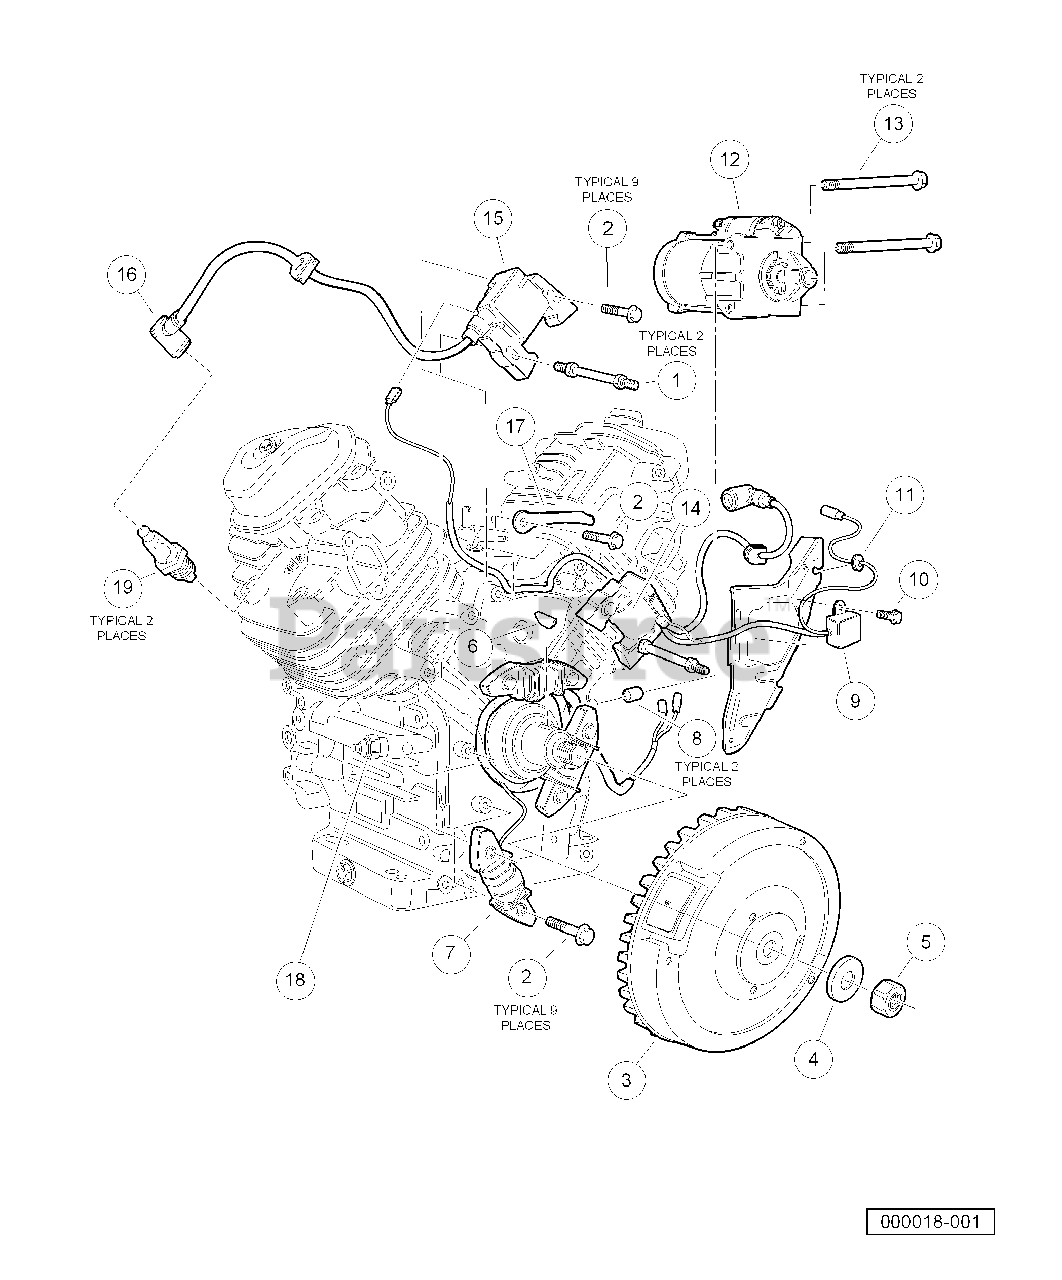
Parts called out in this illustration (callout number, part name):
1	Stud, Engine
2	Bolt, Flange Head, M6 X 1 X 32
4	Washer, M20
5	Nut, Flange, M20
6	Key, Special Woodruff, 25 X 18
7	Coil Assy, Charge, 12-Volt, 20-Amp
8	Pin, Dowel, 10x12
9	Diode Assembly
10	Bolt, Flange Head, M6 X 1 X 8
11	Grommet, Tool
12	Motor, Starter
13	Bolt, Flange Head, M8 X 1.25 X 110
14	Coil Assy, R, Ignition
15	Coil Assy, L, Ignition
16	Cap Assy, Noise Suppressor
17	Clamp, Wire
18	Switch, Oil Pressure
19	Spark Plug, BPR2ES
